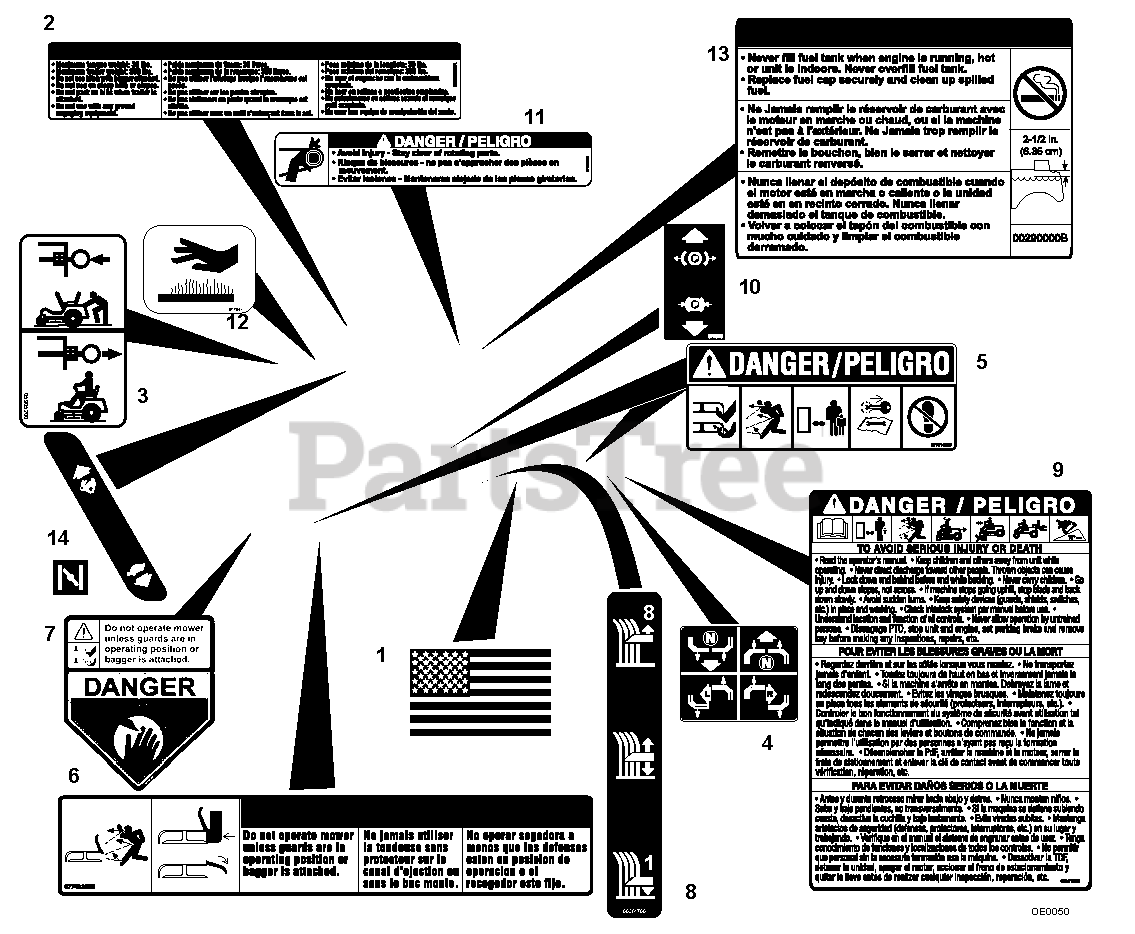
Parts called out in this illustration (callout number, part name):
1	Decal, American Flag
2	Decal, Trailer Hitch
3	Decal, Transmission Disconnect
4	Decal, Instructional Steering
5	Decal, Mower Pan Head Danger
6	Decal, Warning
7	Decal, CPSC Danger
8	Decal, Cut Height
9	Decal, Bilingual Danger
10	Decal, Parking Brake Lever
11	Decal, Danger
12	Decal, Hot Surface
13	Decal, Fuel Warning
14	Decal, Control
